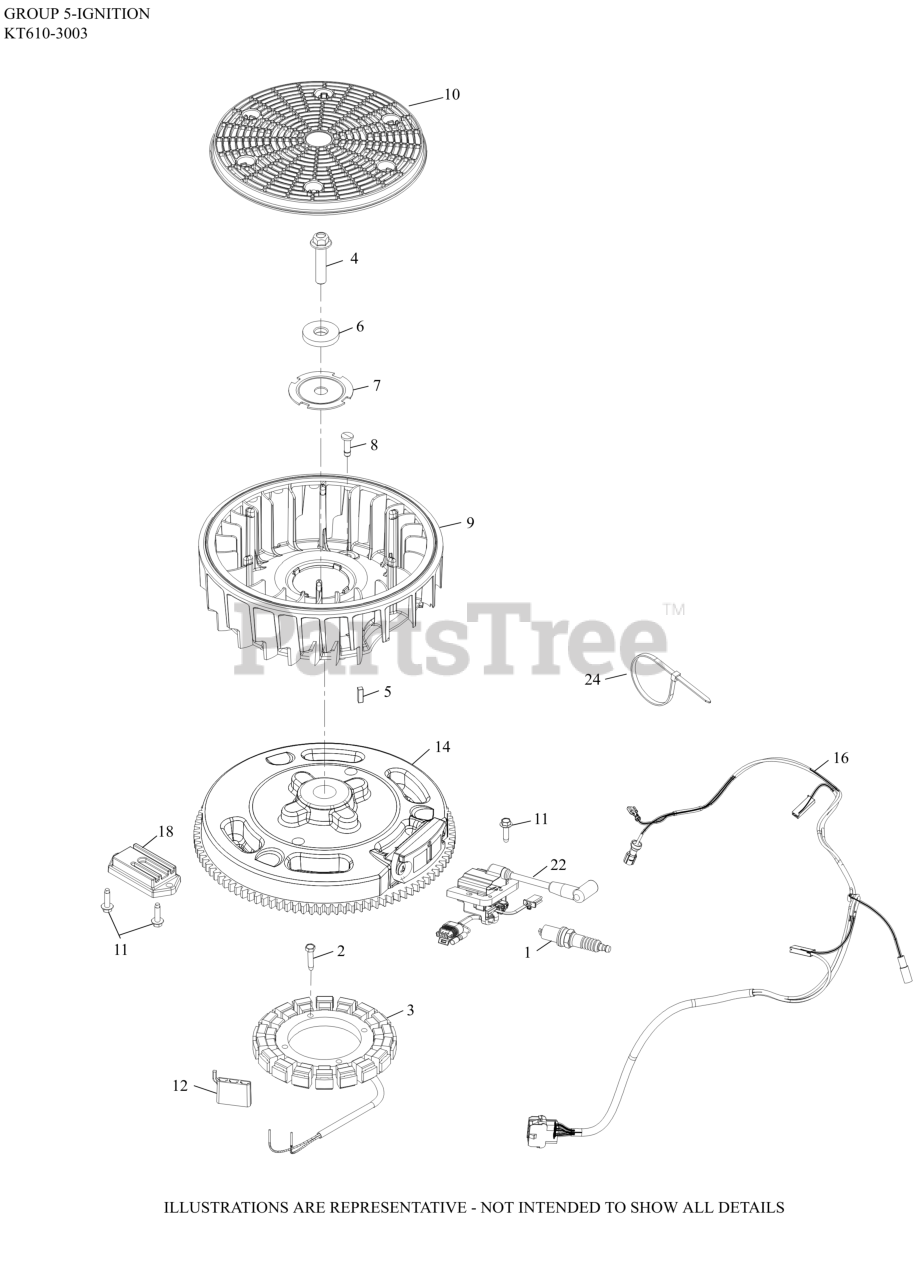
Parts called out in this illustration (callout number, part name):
1	SPARK PLUG, RFI
2	SCREW, THREAD FORMING
3	KIT, 15 / 20 AMP STATOR
4	SCREW, HEX FLANGE
5	KEY, SQUARE
6	WASHER, FLAT
7	PLATE, FAN MOUNTING
8	RETAINER, FLYWHEEL FAN
10	SCREEN, GRASS
11	SCREW, THD FRM-USE 25 086 473-S
12	CONNECTOR
14	FLYWHEEL ASSEMBLY
16	HARNESS, WIRING ASSEMBLY (ECHOKE)
18	REGULATOR/RECTIFIER 12/15A HALF-WAVE STD
22	MODULE, MASTER, CDI (ECHOKE)
22	MODULE, SLAVE, CDI (ECHOKE)
